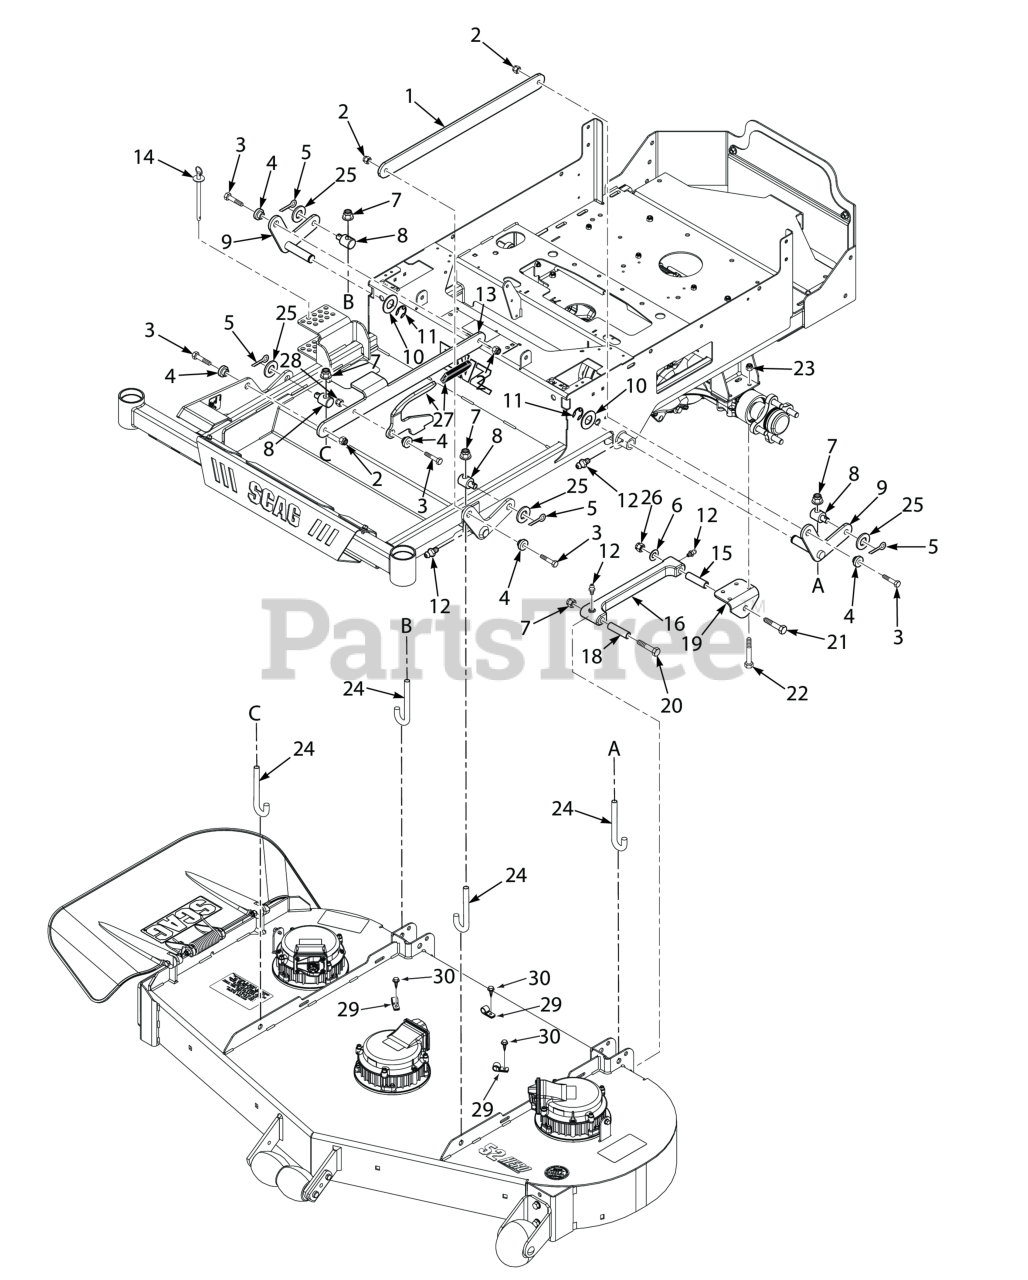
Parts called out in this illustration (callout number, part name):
1	Link, Deck Lift - LH
2	Nut, Flange Elastic Stop Nut, 3/8-16
3	Bolt, Hex Head 3/8-16 x 1-1/4", Kawasaki FX / FT & FT-EFI
4	BUSHING, SPEED ADJUSTMENT LEVER
5	Pin, Cotter 3/16 x 1.0"
6	Flatwasher, 1/2 - .531 x 1.062 x .095
7	HEX LOCKNUT, ELASTIC STOP, 1/2-13
8	Joint, Swivel
9	Lift Bellcrank Weldment
10	Flatwasher, 3/4 (.766 x 1.250 x .060)
11	RETAINING RING, 3/4" EXTERNAL "E"
12	GREASE FITTING, STR. 1/4-28 SELF TAP.
13	Link, Deck Lift - RH
14	Pin Assembly, Deck Height
15	Spacer, Pusharm - Axle
16	Pusharm Assembly, LH
17	Pusharm Assembly, RH
18	Spacer, Pusharm - Deck
19	Bracket, Pusharm
20	Bolt, Hex Head 1/2-13 x 3-1/2"
21	Bolt, Hex Hd. 1/2-13 x 2-1/2" (lower)
22	Bolt, Hex Head 5/16-18 x 3.00"
23	HEX NUT, ELASTIC STOP LOCK, 5/16-18
24	Rod, Deck Lift
25	Flatwasher, 5/8" (.656 x 1.312 x .095")
26	Locknut, Hex 1/2-13 Center Lock
27	Lever Assembly (incl. Grip)
28	HEX NUT, ELASTIC STOP LOCK, 3/8-16
29	Clamp, Cable 1/2" I.D.
30	Screw, Self-Tapping 1/4-20 x 3/4
